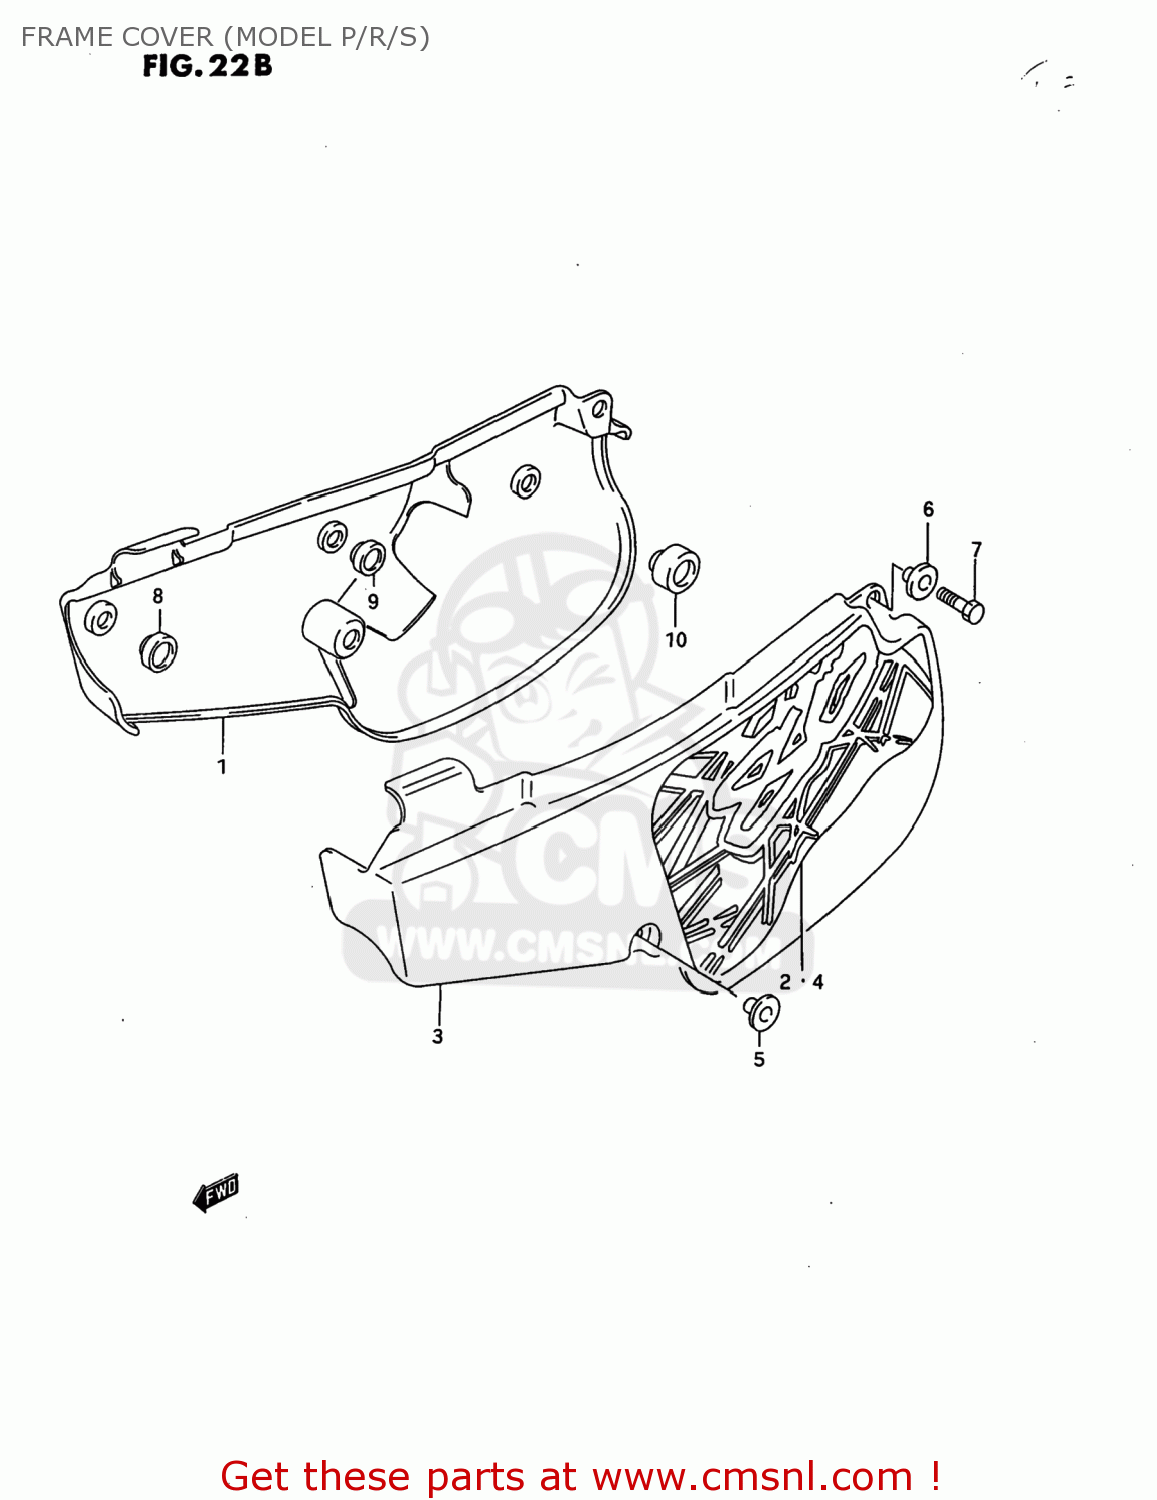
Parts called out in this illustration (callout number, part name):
1	COVER,SIDE,R(WHITE)
2	EMBLEM,FRAME COVER,RIGHT
3	COVER,SIDE,L(WHITE)
4	EMBLEM,FRAME COVER,LEFT
5	WASHER
6	WASHER
7	BOLT
8	CUSHION
9	CUSHION
10	CUSHION
